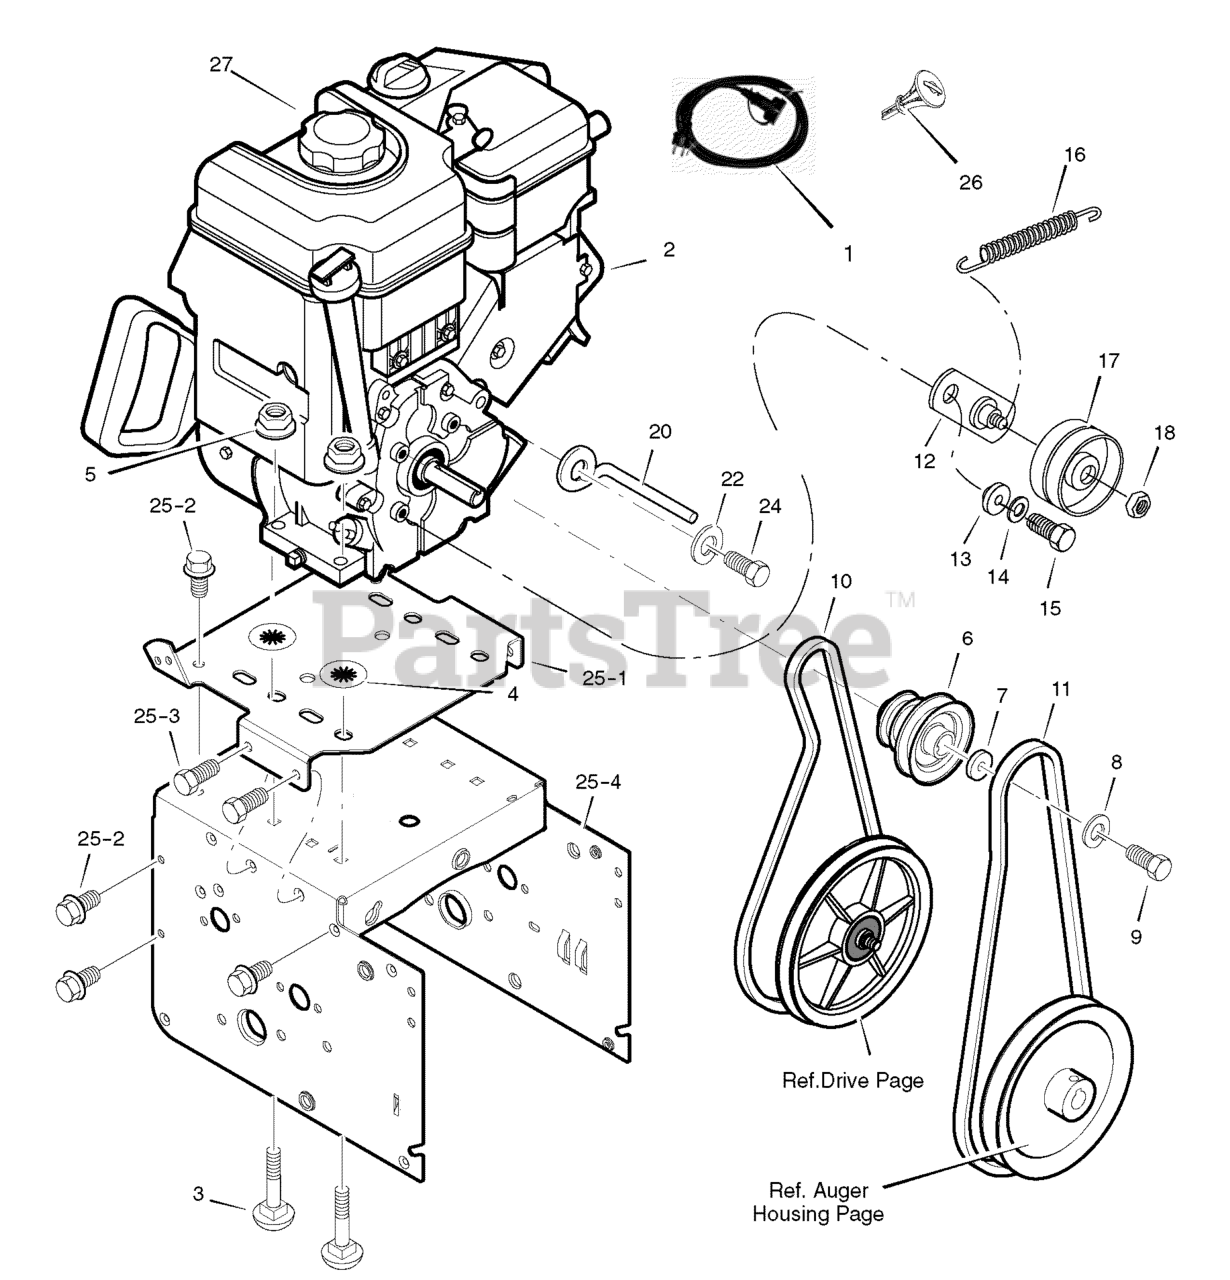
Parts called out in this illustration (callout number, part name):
1	CORD, STARTER
2	ENGINE
3	BOLT, CARRIAGE
4	RETAINER, PUSH
5	NUT
6	PULLEY, ENGINE
7	WASHER
8	WASHER
9	BOLT, HEX 5/16-24 X 1.00 YZ
10	V-BELT, 3L, 33.13
11	V-BELT, 4L, 38.35
12	BRACKET ASSEMBLY, IDLER
13	BUSHING, IDLER BRACKET
14	WASHER, SPLIT
15	BOLT, HEX 5/16-24 X 1.00 YZ
16	SPRING, IDLER TRACTION DRIVE
17	PULLEY, IDLER
18	NUT, JAM 3/8-16
20	GUIDE, ROD BELT
22	WASHER
25	FRAME ASSEMBLY
25-1	PLATE, ENGINE MOUNT
25-2	SCREW
25-4	FRAME, MOTOR BOX
26	KEY, BRIGGS ENGINE
27	GAS CAP
